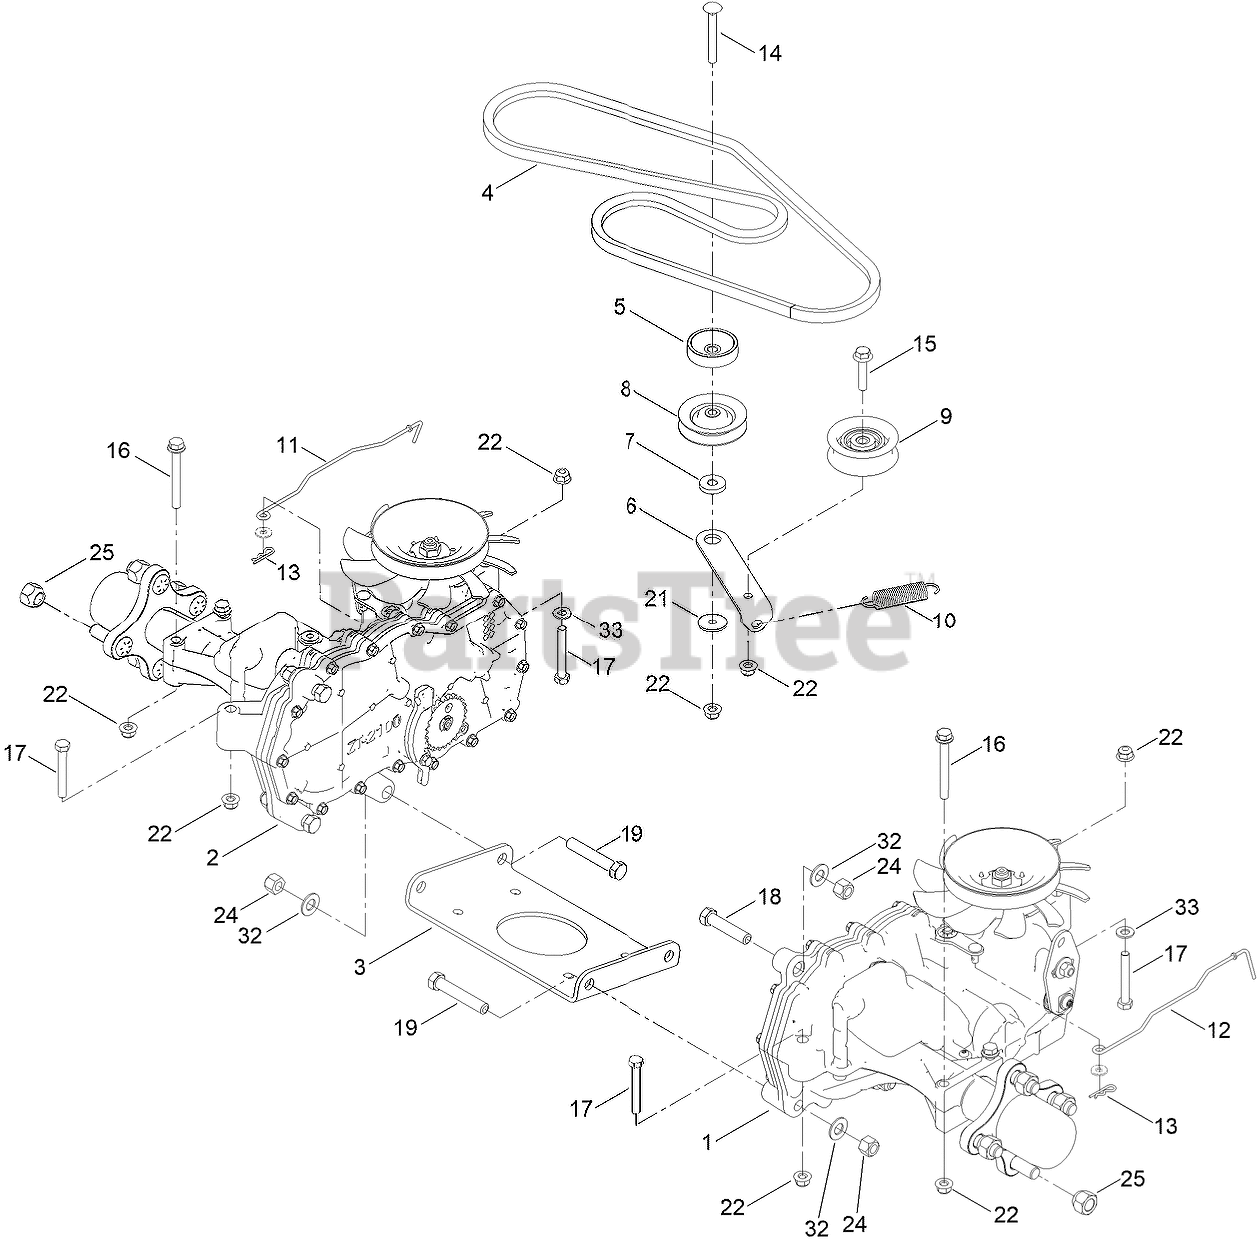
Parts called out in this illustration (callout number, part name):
1	LH HYDRO TRANSAXLE ASM
2	RH HYDRO TRANSAXLE ASM
3	CROSSPLATE-HYDRO
4	V-BELT
5	SPACER
6	ARM-IDLER
7	SPACER-IDLER ARM
9	PULLEY-IDLER, FLAT
10	SPRING-PEDAL, RETURN
11	ROD-BYPASS, RH
12	ROD-BYPASS, LH
14	SCREW-CARR
15	SCREW-HHF
16	SCREW-HHF
17	SCREW-HH
18	SCREW-HH
19	SCREW-HH
21	WASHER-PIVOT
22	NUT-HF, NI
24	NUT-LOCK, NI
25	NUT-LUG
32	WASHER-FLAT
33	WASHER-PLAIN
